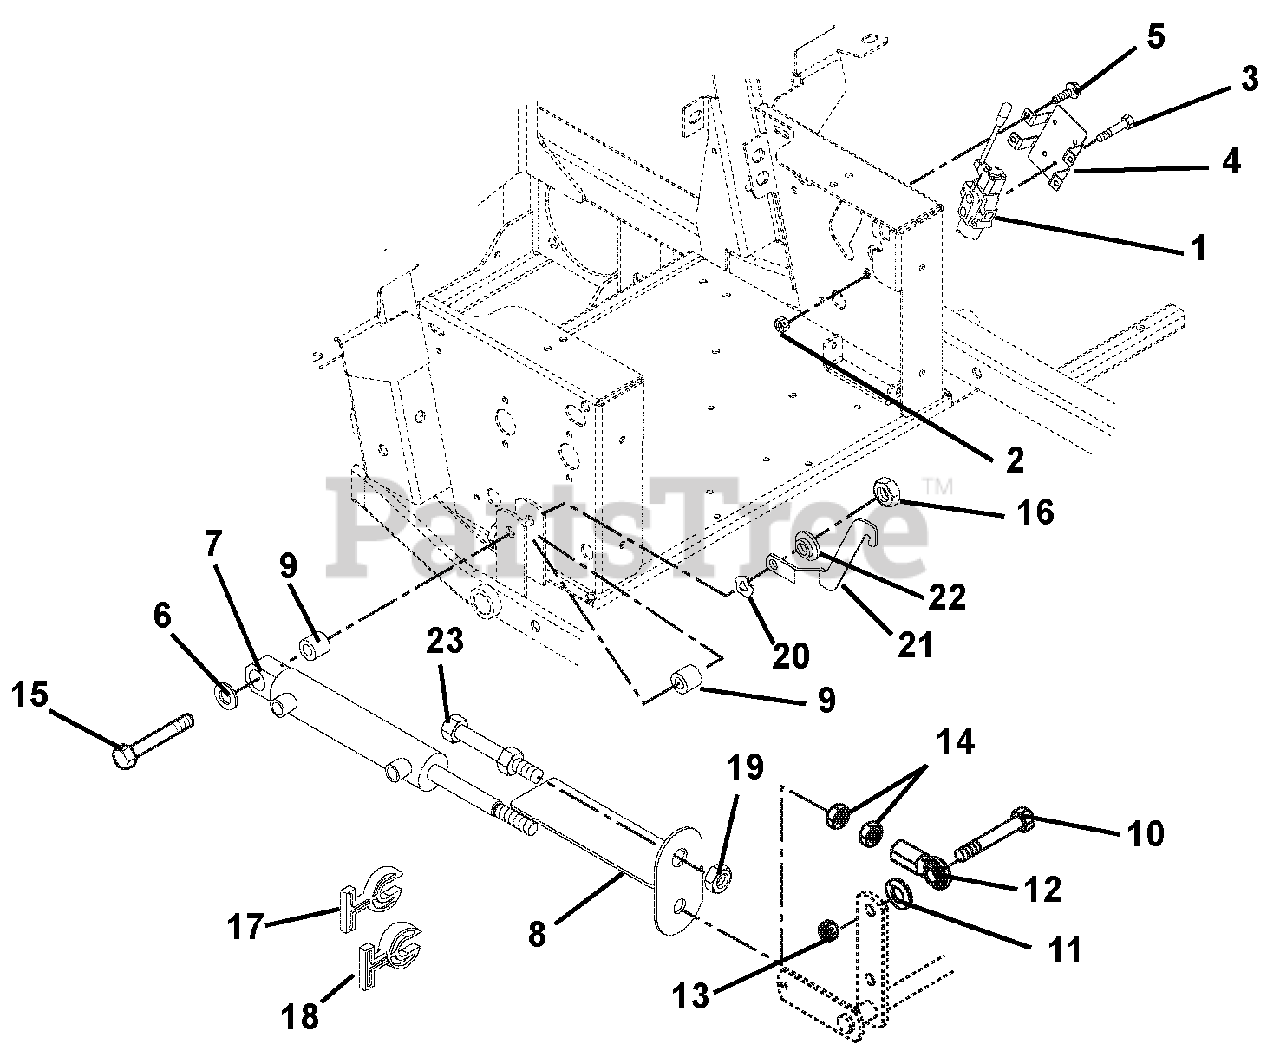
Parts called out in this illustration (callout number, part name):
1	VALVE, HYDRAULIC-BONDIOLI
2	@NUT-LK-TOP-FLG .31-18 YWZC
3	@BLT-HEX .31-18X2.50 GR5 YWZC
4	VALVE MOUNTING BRACKET - BLACK
5	@SCR-TAP .38-16X.50 HWH TR YWZ
6	WSHR-FL-STL .515X1.625X.250 YZ
7	CYLINDER, LIFT
8	CUT INDICATOR/GUARD - BLACK
9	BUSHING, .516X1.000X1.050 LG
10	BLT-HEX .62-11X2.25 YWZC GR8
11	@WSHR-LK .62X.156 REG YWZC
12	ROD END, 5/8 RH - FEMALE
13	@NUT-LK-CTR .62-11 YWZC
14	NUT-JAM .625-18 YWZC
15	@BLT-HEX .50-13X3.75 GR5 YWZC
16	@NUT-LK-TOP-FLG .50-13 YWZC
17	STOP, CYLINDER .34 THK
18	STOP, CYLINDER .680 THK
19	NUT-JAM .75-16 YWZC
20	WASHER-WAVE .760X1.120X.080
21	LATCH, FOOTBOARD HOOK
22	BSHG-FLG .515X.750X.285X1.120
